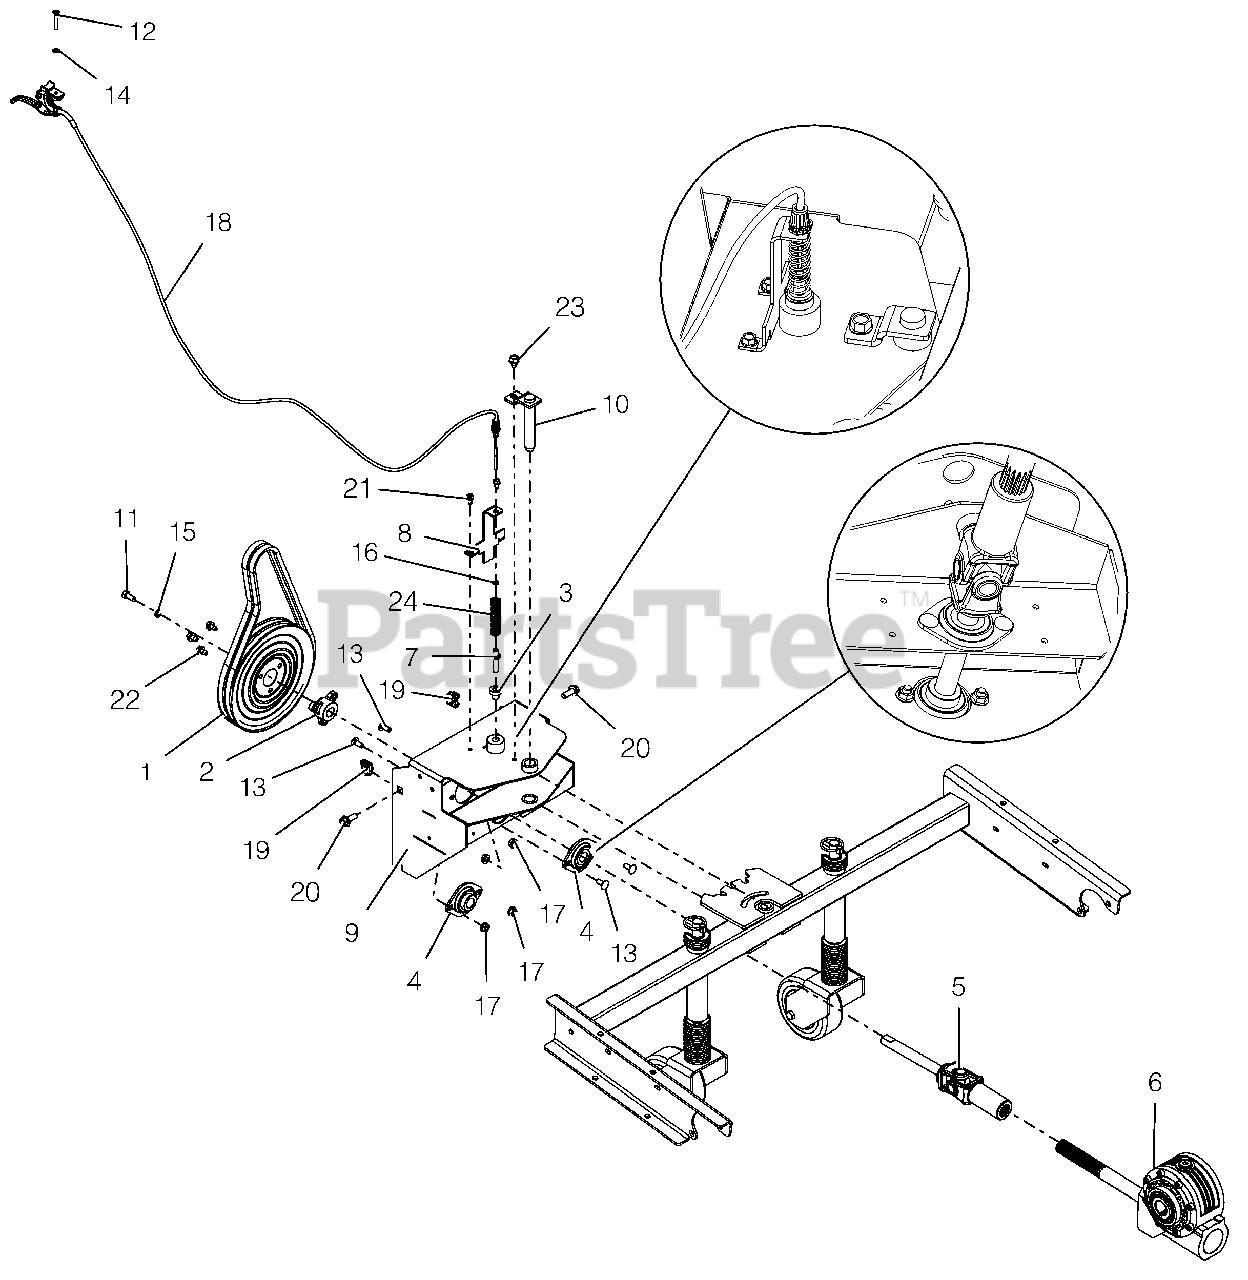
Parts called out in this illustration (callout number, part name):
1	PULLEY, SPIN FORM DUAL GROOVE
2	PULLEY HUB, BOLT-ON D-BORE .75
3	SPACER -FLANGED .390X.500X.781
4	BEARING, 2 BOLT FLANGE -.75 ID
5	DRIVELINE, SERIES 07 (U-JOINT)
6	GEARBOX, WORM - 8.25:1
7	PIN, ADJUSTABLE ANGLE BRUSH
8	BRKT, PIN HOLDER
9	ADAPTER, BRUSH
10	WLDMT, BRUSH PIN
11	BLT-HEX .31-24X.75 YWZC GR5
12	SCR-MCH .25-20X1.50 OVAL HD
13	@BLT-RDHDSQNK .31-18X.75 G5YZ
14	WSHR-LK-INT .250 TH TYA
15	WSHR-LK .312X.097 HVY YWZC
16	@NUT-HEX 10-24 YWZC
17	@NUT-LK-TOP-FLG .31-18 YWZC
18	CABLE, REMOTE BRUSH LOCK
19	NUT-RETNR .38-16 TINRMAN
20	BLT-SERHFWH .375-16X1.0 YWZC
21	SCR-TAP .25-20X.50 HWH TR YWZ
22	@SCR-TAP .31-18X.50 HWH TR YWZ
23	@SCR-TAP .38-16X.50 HWH TR YWZ
24	SPRING, COMPRESSION
